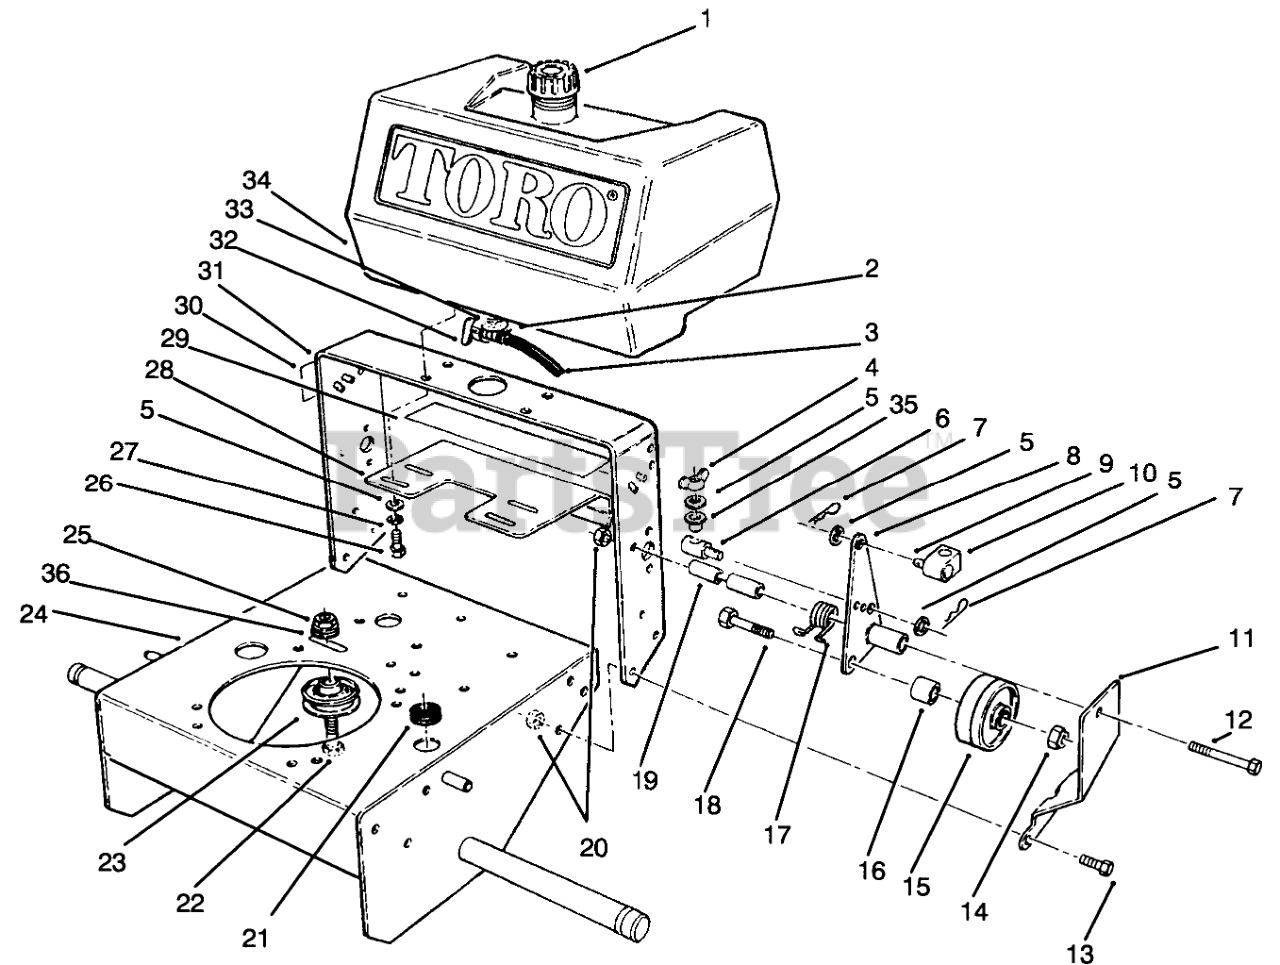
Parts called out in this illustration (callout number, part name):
1	GAS CAP ASM
2	CLAMP-HOSE
3	HOSE-FUEL
4	NUT-WING
5	WASHER-PLAIN
6	FITTING-ROD
7	PIN-COTTER
8	BRACKET-Idler, LH
9	PIN-CLEVIS
10	FITTING-ROD
11	Bracket-LH
12	SCREW-HH
13	SCREW-HH
14	NUT-LOCK, NI
15	IdlerWheel
16	WHEEL IDLER SPACER
17	SPRING-TORSION, LH
18	SCREW-LEVELER
19	SPACER-PIVOT, IDLER
20	NUT-LOCK, NI
21	GROMMET
22	SCREW-HH
23	PULLEY-IDLER
24	FRAME WA RO
25	NUT-HF
26	SCREW-HH
27	WASHER-LOCK
28	Plate
29	DECAL-GROUND SPEED
30	DECAL-FUEL SHUT OFF
31	Frame Rear
32	VALVE-FUEL
33	O-RING
34	FUEL TANK
35	BUSHING-NYLON
36	WASHER-FLAT
